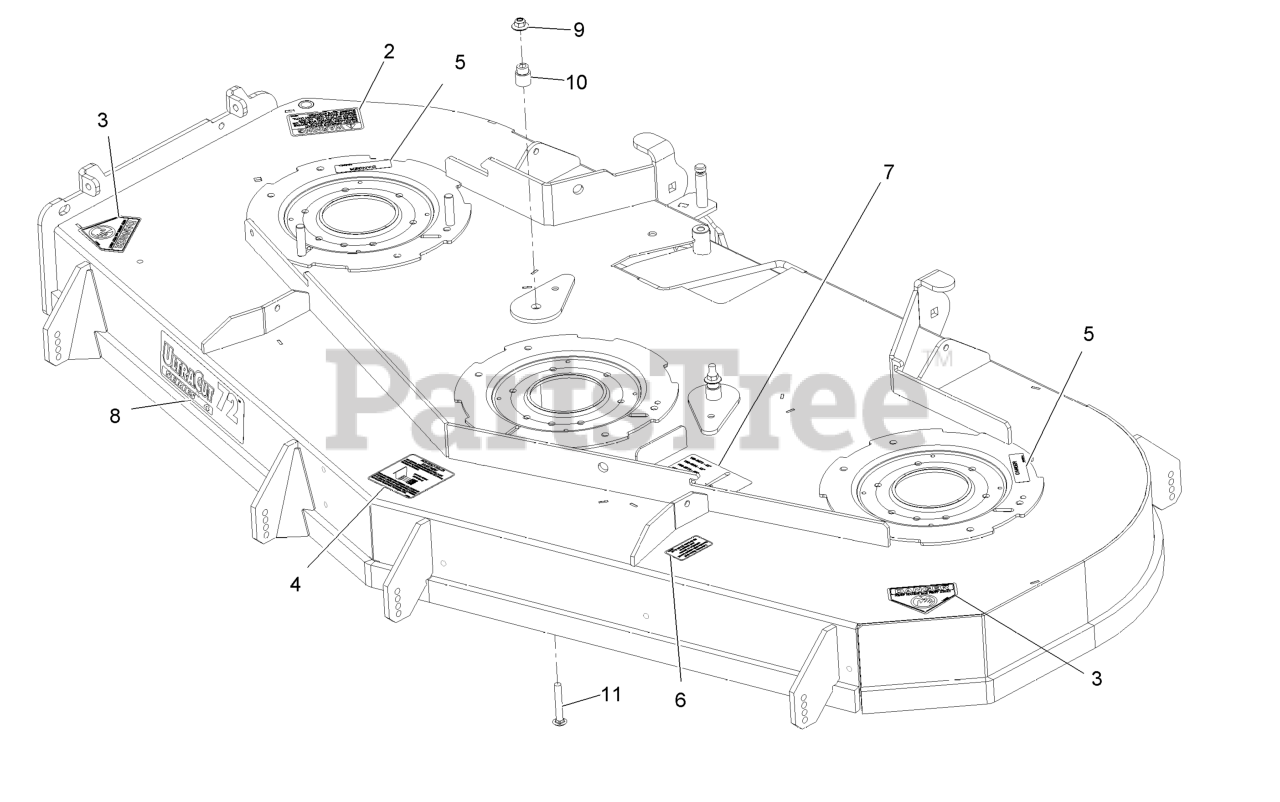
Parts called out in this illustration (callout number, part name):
2	DECAL-WARNING, DISCHARGE
3	DECAL-DANGER
4	DECAL,ANTISCALP
5	DECAL-COVER, MISSING
6	DECAL,BOLT TORQUE
7	DECAL,BELT ROUTING
8	DECAL,ULTRACUT 72 SERIES
9	Nut-Nyloc 3/8-16 Flg
10	BUSHING-IDLER
11	SCREW-CARR
